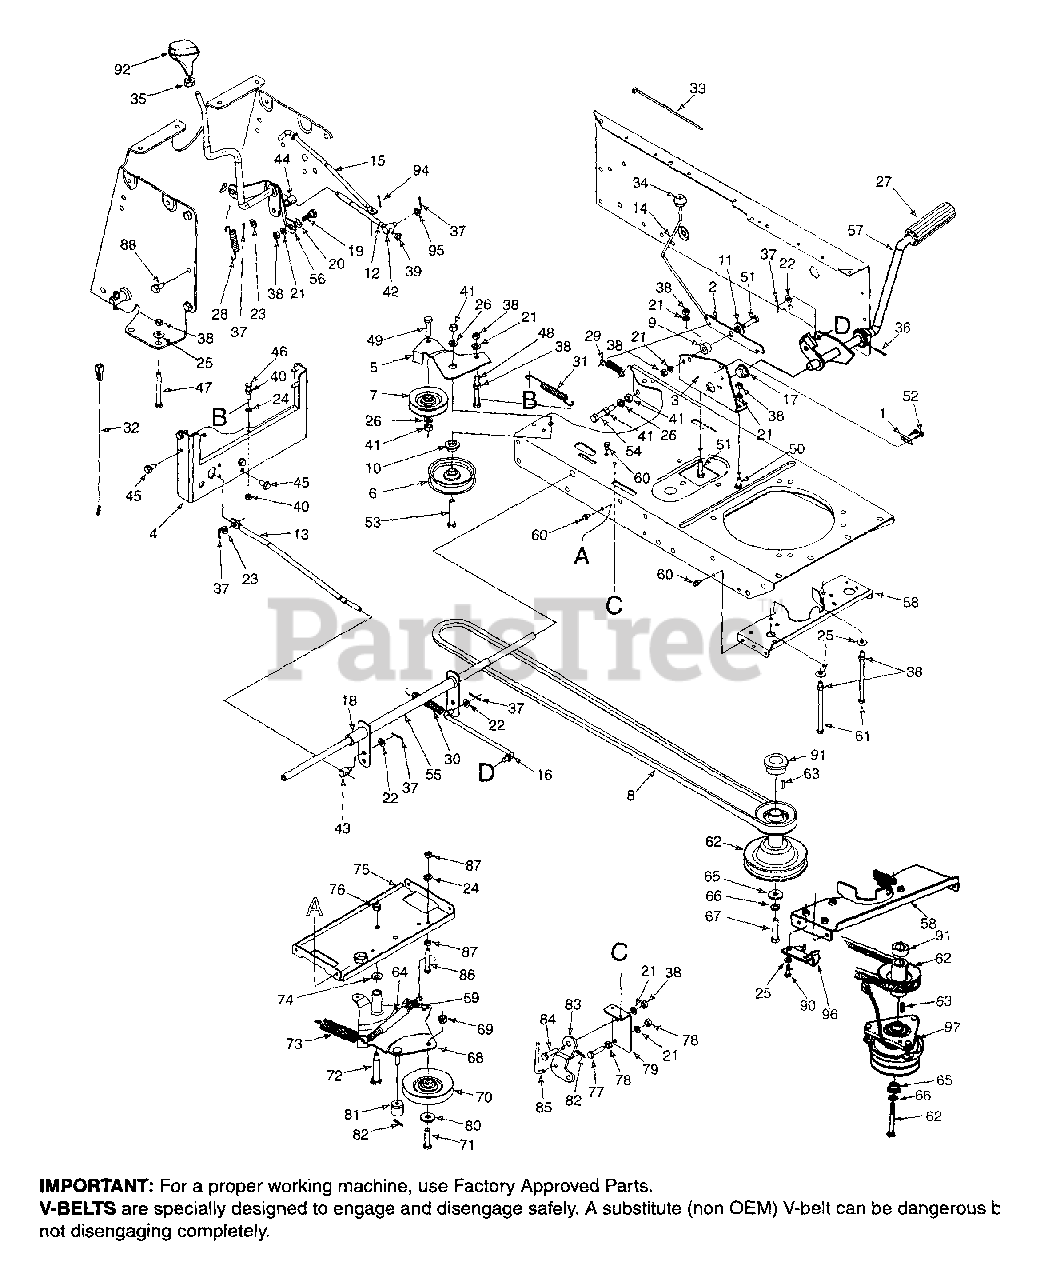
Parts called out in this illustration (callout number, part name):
1	Switch Plate
7	Idler Pulley
8	"V" - Belt
9	Spacer .34" I.D. x .44" Lg.
10	Shld. Spacer .38" I.D.
11	Shld. Spacer
12	Speed Selector Rod
13	Neutral Return Rod
14	Brake Lockout Rod
15	Hydro Disengagement Rod
16	Brake Link Rod
17	Hex Flange Bearing
18	Nyliner Flange Bearing
19	Shld. Bolt
20	Spr. Wash. 7/16" I.D.
21	L-Wash. 5/16" I.D.
22	Fl-Wash. 5/16" I.D.
23	Fl-Wash. .38" I.D.
24	L-Wash. 1/4" I.D.
25	Bell-Wash. .345" I.D.
26	L-Wash. 3/8" I.D.
27	Foot Pad
28	Ext. Spring 2.75" Lg.
29	Ext. Spring 2.51" Lg.
30	Ext. Spring 4.74" Lg.
31	Ext. Spring 4.97" Lg.
32	Transmission Wire
33	Cable Tie
34	Ball Knob
35	Hex Jam Nut 3/8-16 Thd. (Gr. 5)
36	Cotter Pin 1/8" Dia. x 1" Lg.
37	Cotter Pin 3/32" Dia. x 1" Lg.
38	Hex Nut 5/16-18 Thd. (Gr. 5)
39	Hex Jam Nut 5/16 Thd. L.H.
40	Hex Nut 1/4-20 Thd. (Gr. 5)
41	Hex Nut 3/8-16 Thd. (Gr. 5)
42	Ferrule 5/16-24 Thd. L.H.
43	Ferrule 5/16-18 Thd.
44	Ferrule 3/8-24 Thd.
45	Hex Wash. TT-Tap Scr. 5/16 x .75" Lg.
46	Hex Bolt 1/4-20 x 1.25" Lg.
47	Hex Bolt 5/16-18 x 3" Lg.
48	Hex Bolt 5/16-18 x 2.75" Lg.
49	Hex Bolt 3/8-16 x 1.5" Lg.
50	Hex Bolt 5/16-18 x .75" Lg.
51	Hex Bolt 5/16-18 x 1.25" Lg.
52	Hex HD Tapp Scr. #10-16 x .75" Lg.
53	Hex Bolt 3/8-16 x 2.25" Lg.
54	Hex Bolt 3/8-16 x 2" Lg. (Gr. 5)
57	Hydro Foot Pedal Ass'y.
60	Hex Wash. TT-Tap Scr. 1/4-20 x .5" Lg.
61	Hex Bolt 5/16-18 x 5.25" Lg.
62	Engine Pulley
63	Sq. Key 1/4 x 1.5" Lg.
64	Convoluted Conduit
65	Fl-Wash. .45" I.D. x 1.25"
66	L-Wash. 7/16" I.D.
67	Hex Bolt 7/16-20 x 1.5" Lg.
68	Idler Brkt. Deck Ass'y.
69	Hex Cent. L-Nut 3/8-24 Thd.
70	Idler Pulley
71	Hex Bolt 3/8-24 x 1.5" Lg.
72	Shld. Bolt .498" Dia. x 2.05"
73	Ext. Spring 6.12" Lg.
74	Bell-Wash. .38" I.D. x .88" O.D.
76	Hex Cent. L-Nut 3/8-16 Thd.
77	Hex Bolt 5/16-24 x 1.25" Lg.
78	Hex Nut 5/16-24 Thd. (Gr. 5)
79	Parking Brake Mtg. Brkt.
80	Fl-Wash. .40" I.D. x .875" O.D.
81	Spacer
82	Hairpin Clip
83	Deck Control Pivot Brkt.
84	Shld. Bolt .437" Dia. x .162"
85	Deck Control Rod
86	Hex Bolt 1/4-20 x 2" Lg.
87	Hex Nut 1/4-20 Thd.
88	Hex AB-Tap Scr. 5/16 x .75"
90	Hex Bolt 5/16-18 x .75" Lg.
91	Clutch Spacer
92	Shift Knob
94	Hairpin Clip
95	Fl-Wash. .344" I.D. x .75" O.D.
